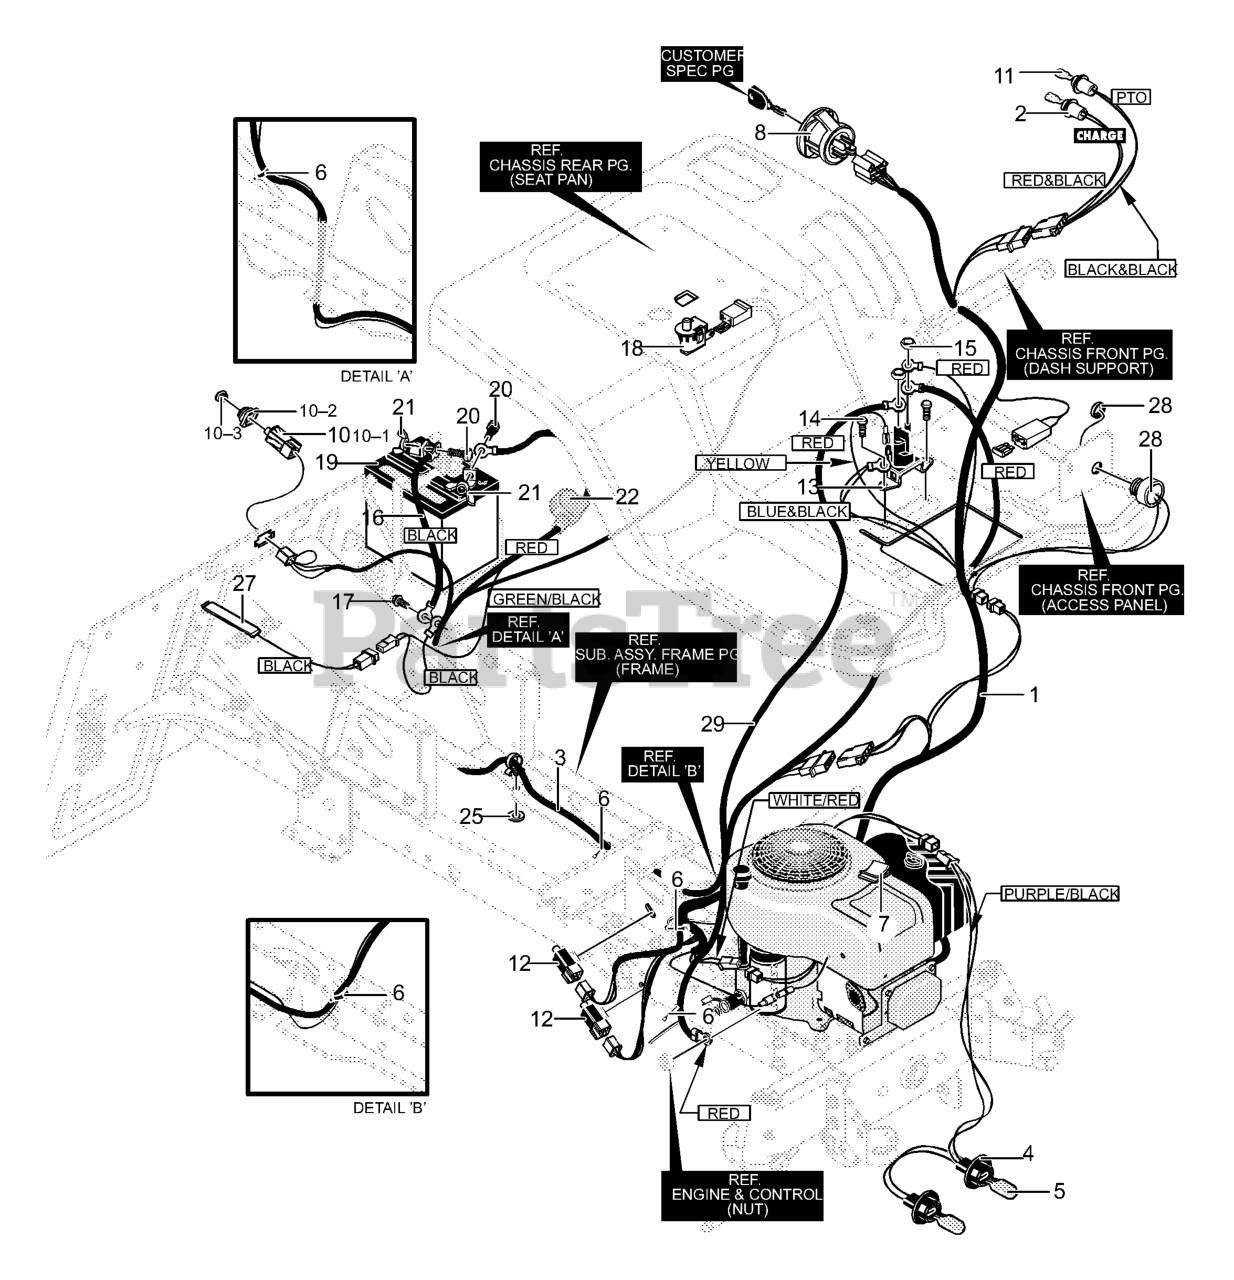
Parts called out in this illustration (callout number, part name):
1	Wire Harness
2	Indicator Harness
3	Rear Harness
4	Wire Harness for Headlights
5	Bulb, Headlamp
6	Cable Tie
7	Wire Clip, Adhesive
8	Switch, Ignition
10	Assy, Switch Double Pole Delta
10-1	Switch, Double
10-2	Boot, Switch
10-3	Switch Cap
11	Bulb, Indicator
12	Switch, Limit
13	Solenoid
14	Screw 1/4x.50
15	Nut, 1/4-20
16	Ground Wire
17	Screw, 1/4x.50
18	Seat Switch
19	Battery 6 Plate
20	Bolt, 1/4-20x.63
21	Wing Nut
22	Battery Boot
25	Flatwasher
27	Tape Switch
28	Buzzer, For Bag Full
29	Wire, Lead Solenoid to Starter
